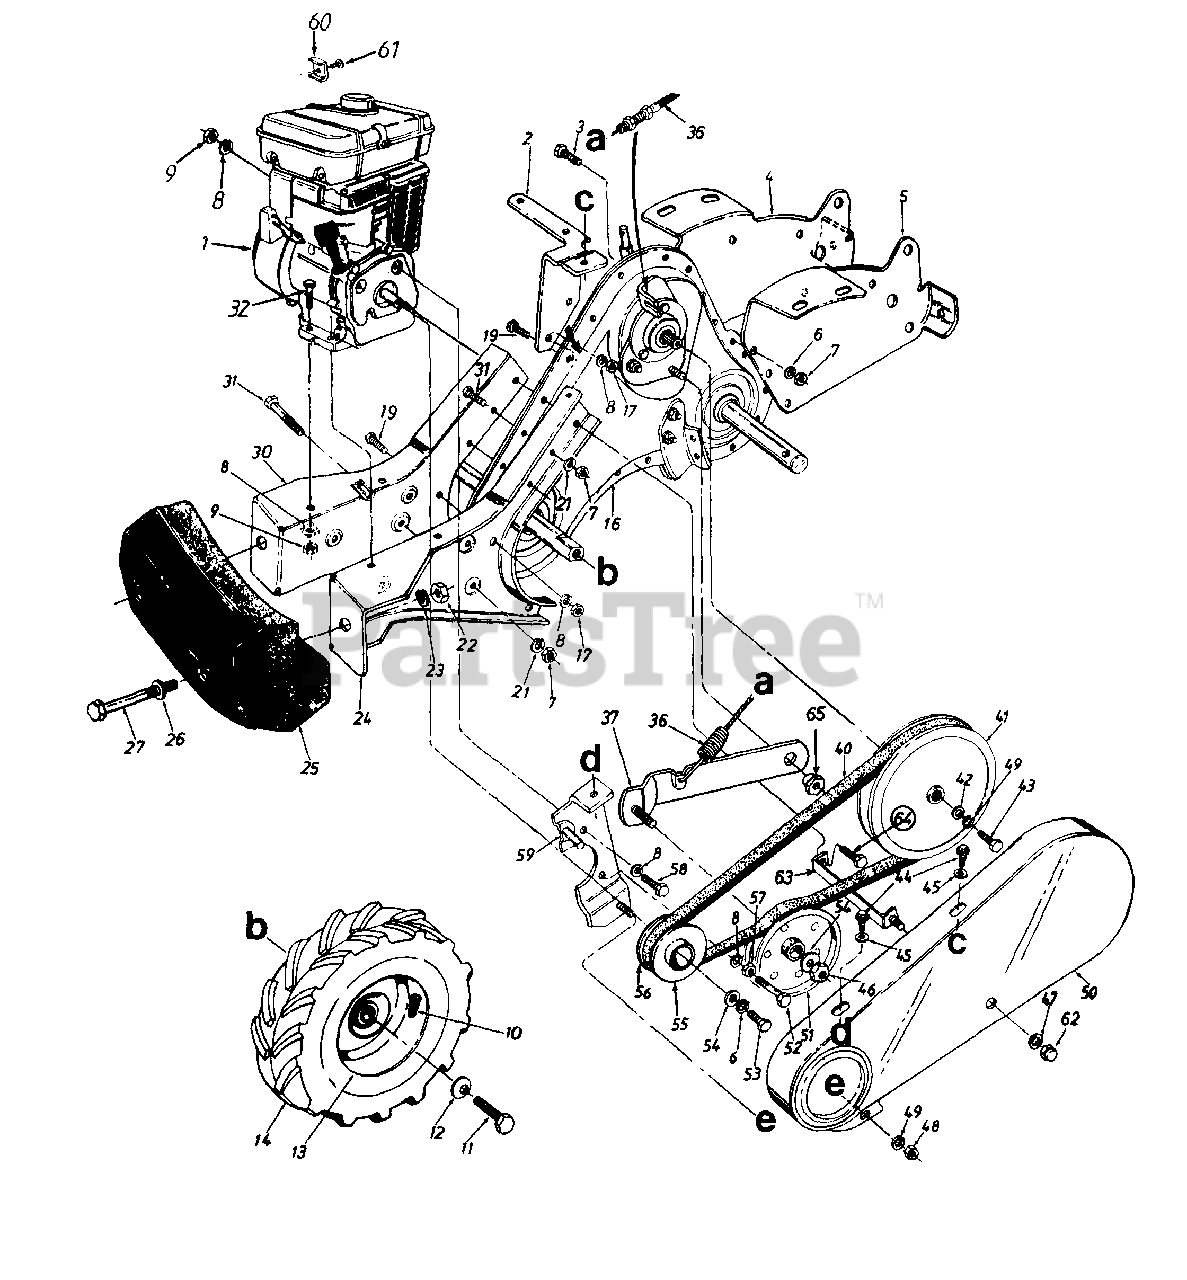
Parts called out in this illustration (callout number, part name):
1	Engine
7	Hex Nut 3/8-16 Thd.
8	L-Wash. 5/16" I.D.
9	Hex Nut 5/16-18" Thd.
10	Air Valve
11	Hex Bolt 5/16-24 x .62" Lg.
12	Bell-Wash. .345" I.D. x .88"
13	Wheel Rim Ass'y. Only
14	L.H. Wheel Ass'y. Comp.
17	Hex Nut 5/16-18 Thd.
19	Hex Bolt 5/16-18 x .75" Lg.
21	L-Wash. 3/8" I.D. - H.D.
22	Hex Nut 1/2-13 Thd.
23	L-Wash. 1/2" I.D.
26	Fl-Wash. .510" I.D. x 1.0"
27	Hex Belt 1/2-13 x 5.00" Lg.
32	Hex Bolt 5/16-18 x 1.50"
36	Clutch Control Cable 46" Lg.
37	Idler Bracket Ass'y.
40	"V"-Belt
41	Fl-Pulley 8" O.D.
42	Fl-Wash. 1/4" I.D. x .93" O.D.
43	Hex Bolt 1/4-28 x .75" Lg.
44	Hex Wash. Hd. S-Tap Scr. 1/4-20 x .50" Lg.
45	Fl-Wash. .281" I.D. x .625"
46	Hex Cent. L-Nut 3/8-24 Thd.
47	Fl-Wash. .266" I.D. x .625" O.D.
48	Hex Nut 1/4-20 Thd.
49	L-Wash. 1/4" I.D.
51	Fl-Idler w/FIanges 3.75" O.D.
52	Hex Bolt 5/16-24 x 1.75"
53	Hex Bolt 3/8-24 x 1.00" Lg.
54	Fl-Wash. 3/8" I.D. x 1.00"
55	Outer Engine Pulley Half
56	Inner Engine Pulley Half
57	Hex Nut 5/16-24 Thd.
58	Hex Bolt 5/16-24 x .62" Lg.
61	Hex Sems Scr. #10-32 x .62"
62	Hex Cap Nut 1/4-28 Thd.
63	Belt Cover Brkt. Ass'y.
64	Hex Bolt 5/16-18 x 1" Lg. (Gr. 5)
65	Shld. Nut
